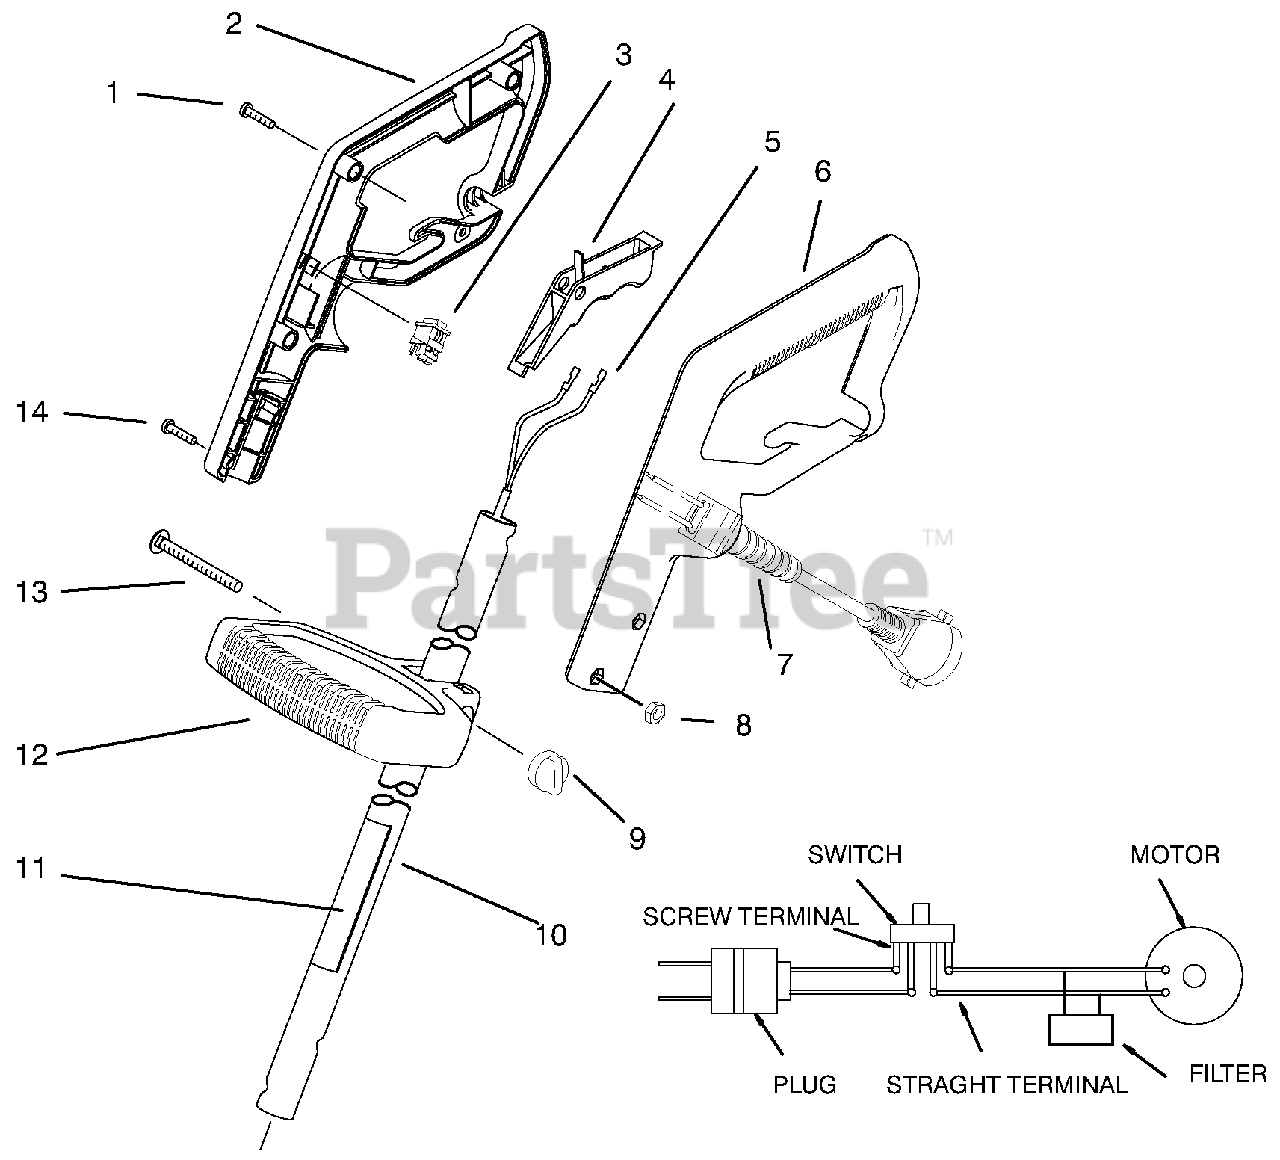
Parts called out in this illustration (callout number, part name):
1	Screw-Pan HdTapping
2	Grip-Hand R.H.
5	Harness-Wire
6	Grip-Hand L.H.
7	Cord-Power
8	Nut-Lock
10	Tube Assembly (Incl. Ref. #11)
11	Decal-Safety
12	Handle-Mid
13	Screw-Carriage
14	Screw-Pan Hd.
